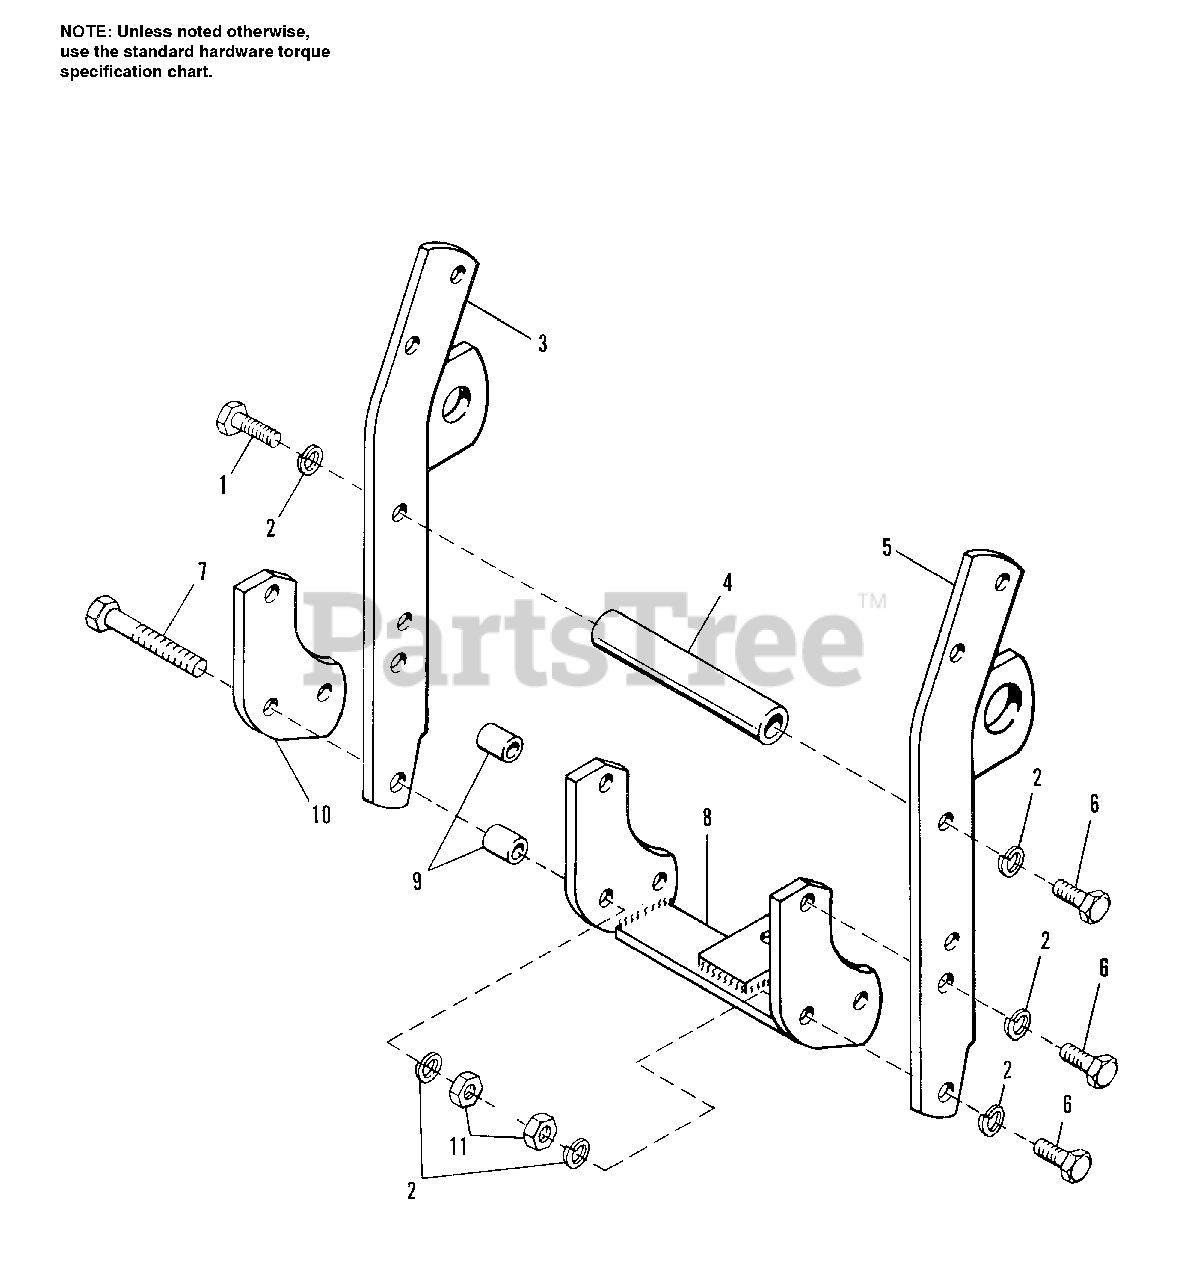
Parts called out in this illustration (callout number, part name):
1	CAPSCREW, Hex Hd, 7/16-14 x 1-3/4
2	LOCKWASHER, 7/16
3	BAR ASSEMBLY, Upright
5	BAR ASSEMBLY, Upright
6	CAPSCREW, Hex Hd, 7/16-14 x 1-1/4
7	CAPSCREW, Hex Hd, 7/16-14 x 2-3/4
8	BAR ASSEMBLY, Draw
11	NUT, Hex, Full, 7/16-14
